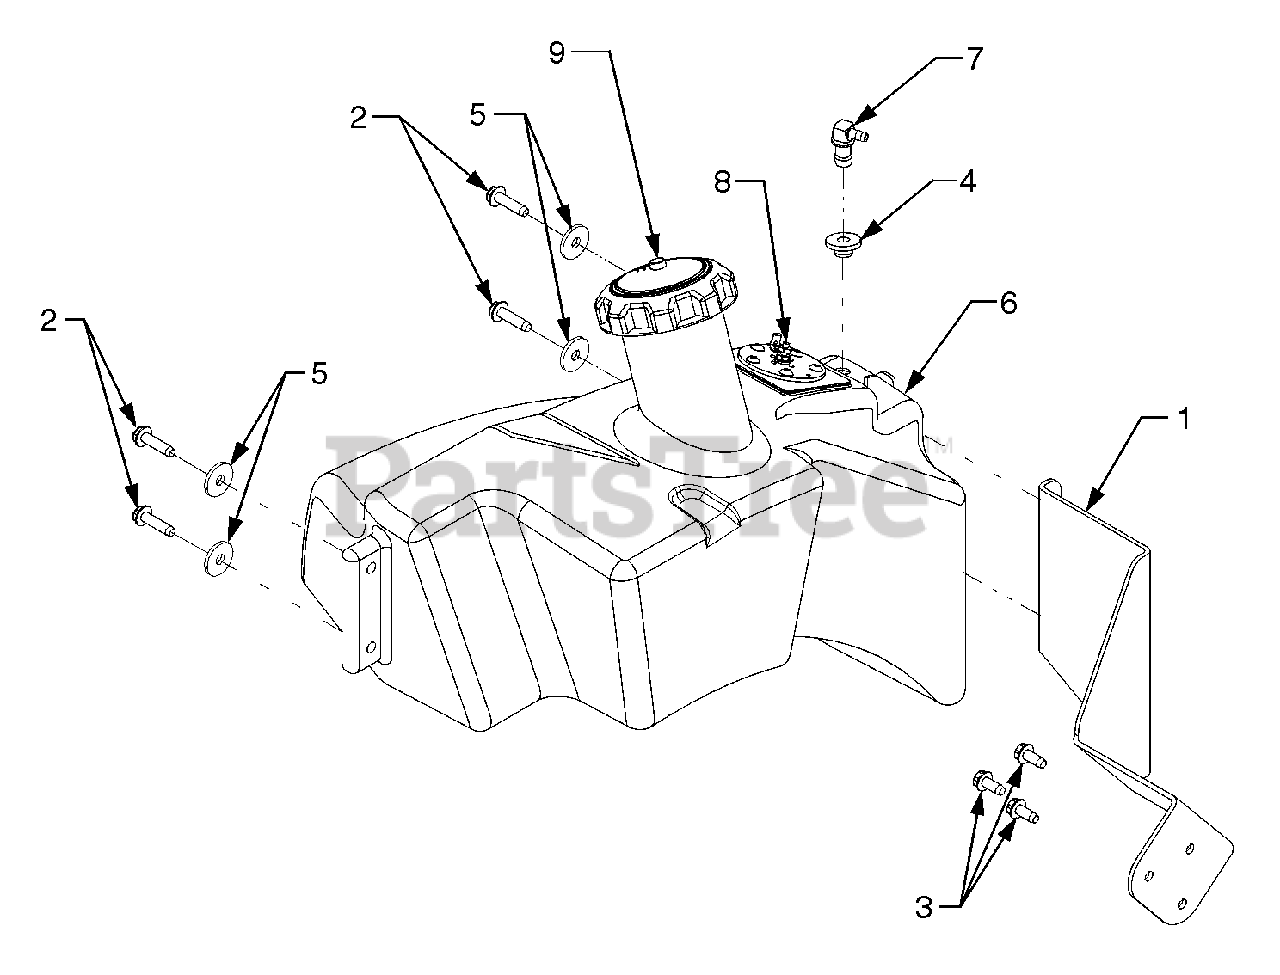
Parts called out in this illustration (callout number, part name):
1	Bracket, Front Tank Mtg.
2	Screw, Hex Wash Hd Tapp 5/16-18 x 1.25
3	Screw, Hex Wash Hd Tapp 5/16-18 x .75
4	Bushing, Rubber
5	Washer, Flat, .344 x 1.125 x .12
6	Tank, Fuel
7	Fitting, Fuel Return
8	Sensor, Fuel Level
9	Cap, Fuel - Diesel
